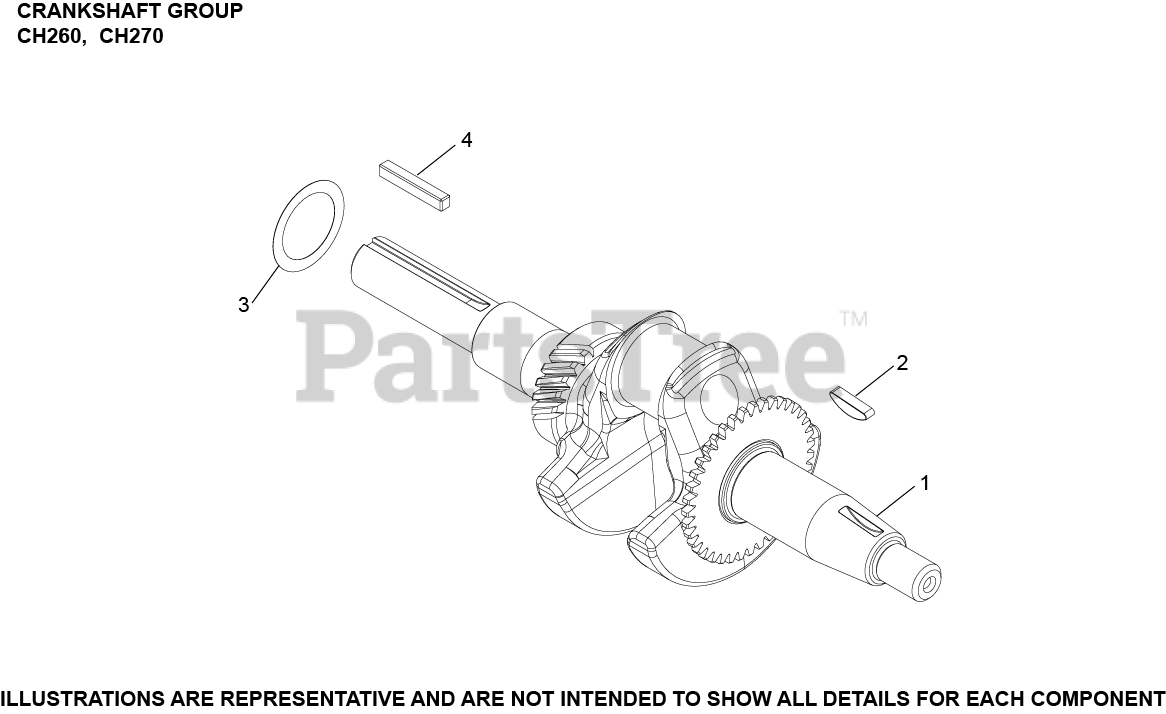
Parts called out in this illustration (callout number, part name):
1	CRANKSHAFT ASSEMBLY
2	KEY, FLYWHEEL
3	KIT, THRUST SHIM
